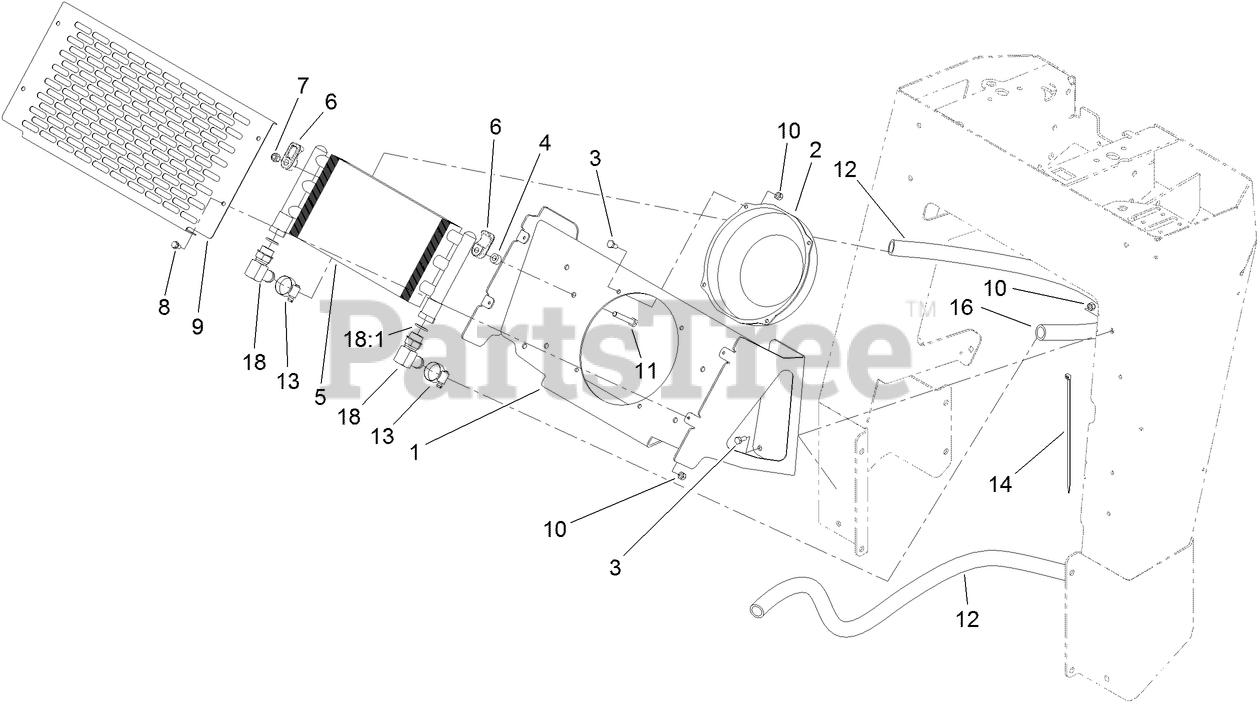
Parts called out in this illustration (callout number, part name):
1	MOUNT-COOLER
3	SCREW-HH
4	SPACER
5	EXCHANGER-HEAT
6	CLAMP-COOLER, OIL
7	NUT-LOCK, NI
8	SCREW-HWH
9	COVER-COOLER
10	NUT-LOCK, NI
11	SCREW-HH
12	HOSE-RETURN
13	CLAMP-HOSE
14	TIE-CABLE
16	HOSE-COOLER
18	FITTING
18:1	O-RING
